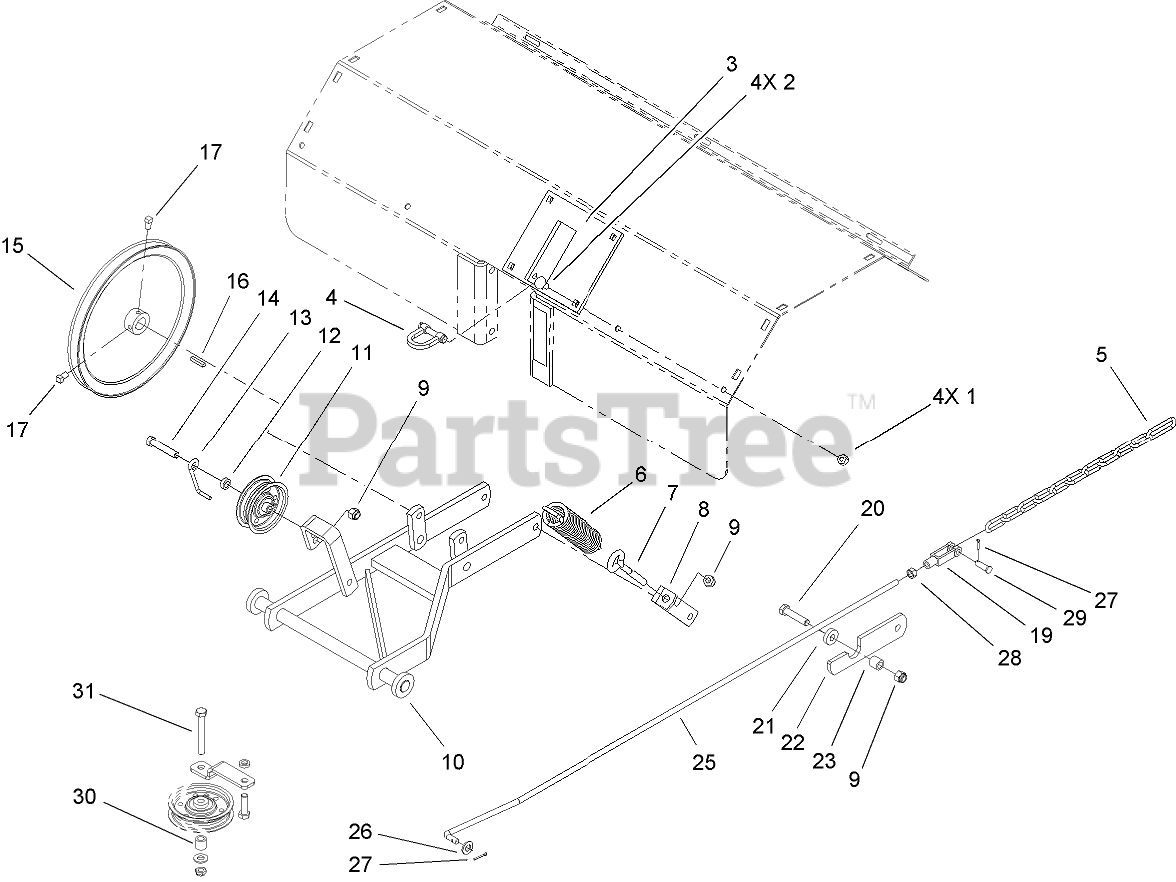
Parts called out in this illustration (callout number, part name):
1	NUT-LOCK, NI
2	BOLT-CARR
3	HITCH ASM
4	CLEVIS ASM
5	CHAIN-LIFT
6	SPRING
7	EYEBOLT
8	BRACKET-SPRING
9	NUT-LOCK, NI
10	HITCH ASM
11	PULLEY-IDLER
12	Spacer
13	GUIDE-BELT
14	SCREW-HH
15	PULLEY
16	KEY-STRAIGHT
17	SCREW-SQH
19	YOKE-ADJUSTABLE
20	SCREW-HH
21	Washer
22	CATCH-SPRING
23	SPACER
25	ROD-LIFT
26	WASHER-FLAT
27	PIN-COTTER
28	NUT-HEX
29	PIN-CLEVIS
30	SPACER
31	SCREW-HH
